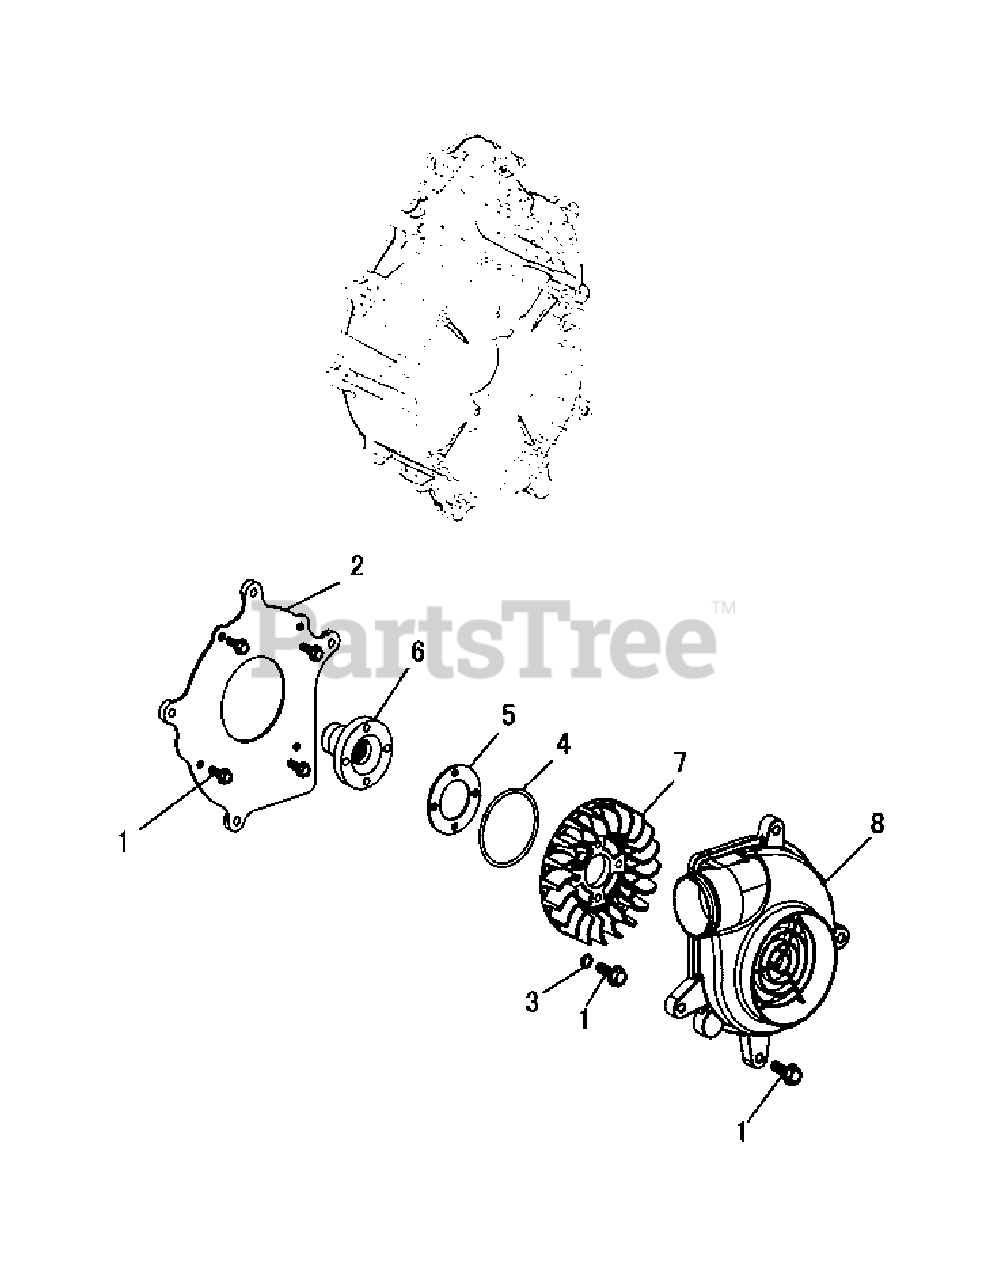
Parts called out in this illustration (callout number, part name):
1	Flange Bolt M6X20
2	Mounting Board
3	Washer 6×11×1.5
4	O-Ring 64.4X3.1
5	Plate-Fan Station
6	Starter Pulley
8	Cover-Outer Clutch
